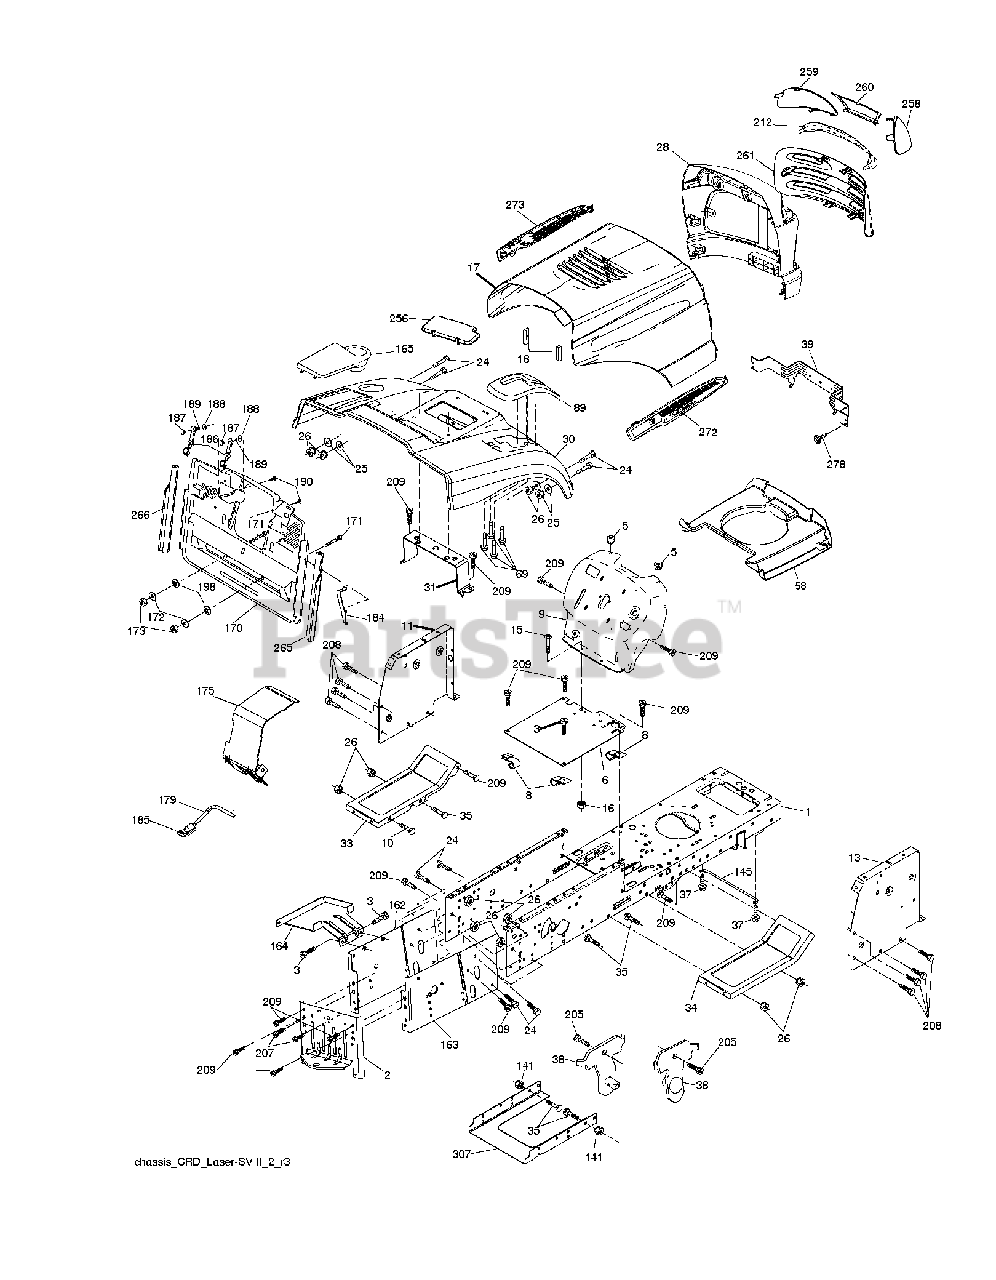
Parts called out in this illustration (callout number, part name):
1	CHASSIS
3	SCREW 3/8-16X3/4
5	BUMPER.RUBBER.HOOD
8	CLIP,INSULATOR
10	BOLT D
11	PANEL.DASH.LH.LTX
13	PANEL ASM, DASH RH
16	NUT
18	BUMPER.HOOD.LARGE.1.75"
25	WASHER
26	NUT
31	BRACKET SUPPORT FENDER
39	BRACKET PIVOT
69	SCREW.HI-LO.CONSOLE
141	NUT LOCK FLG 3/8-16 UNC
145	ROD.PIVOT.HOOD
164	SUPPORT
171	BOLT
172	WASHER
186	LATCH ASSY
187	WELDNUT
189	LOCKWASHER
207	SCREW, 5/16-18 X 1/2
208	SCREW 3/8-16X1/2
209	SCREW, 3/8-16X3/4
278	SCREW.#10 X 0.750.BOS THREAD
